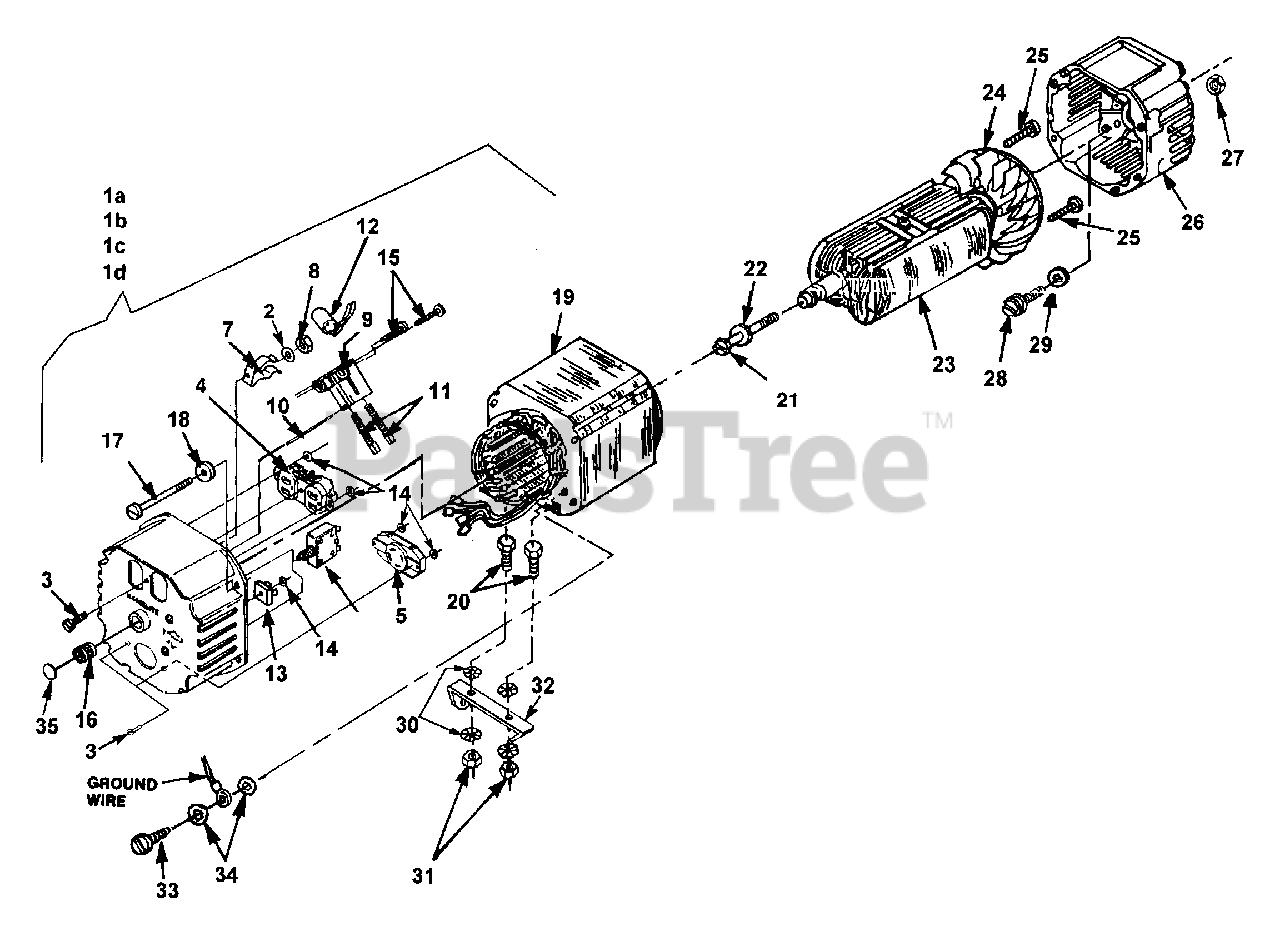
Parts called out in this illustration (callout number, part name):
1A	COMPLETE BRUSH HEAD
1B	COMPLETE BRUSH HEAD
1C	COMPLETE BRUSH HEAD
1D	COMPLETE BRUSH HEAD
2	WASHER-Lock (ext.)
3	SCREW-Mach. Pan Hd. (6-32 X 1/2")
4	RECEPTACLE-Duplex (Nema 5-15R)
5	RECEPTACLE-Locking (120V/240V) (Nema L14-20R)
7	CLIP-Spring Cap
8	NUT-Hex (6-32)
9	BRUSH HOLDER
11	BRUSH
12	CAPACITOR (w/Lead)
13	RECTIFIER
14	WASHER-Shaft Retention
15	SCREW-Pan Hd. (6-19 X 3/4
16	BEARING-Needle
17	BOLT-Stator (4400 Watts)
18	WASHER-Flat
19	STATOR (4400 Watts)
20	SCREW- Hex Hd. (5/16-18 X 3/4")
21	BOLT-Rotor (4400 Watts)
21	BOLT-Rotor (5500 Watts)
22	WASHER-Lock (5/16")
23	ROTOR (4400 Watts)
23	ROTOR (5500 Watts)
24	FAN-Generator
25	SCREW-Pan Hd. (6-19 X 3/4")
26	END BELL
27	NUT-Hex (1/4-20)
28	SCREW-Hex Hd. (5/16-24 X 3/4")
29	WASHER-Lock
30	WASHER-Lock (int./ext.)
31	NUT-Hex (5/16-18)
32	SUPPORT-Engine
33	SCREW-Taptite (10/24 X 3/4")
34	WASHER-Lock (int./ext.)
35	PLUG-Expansion
